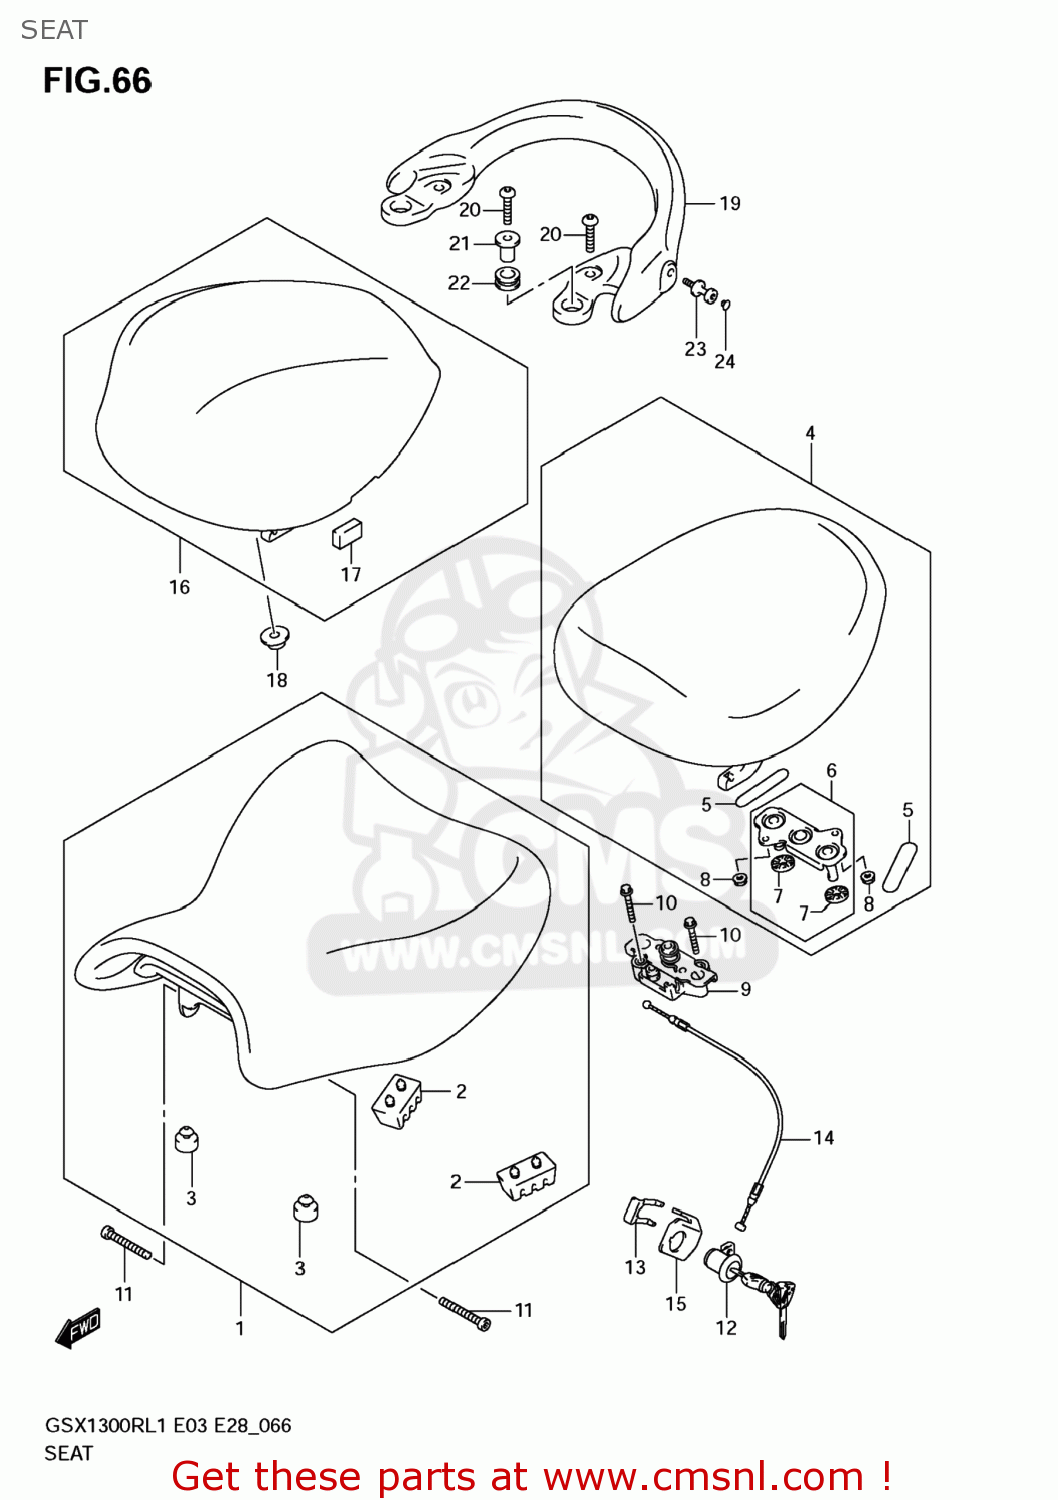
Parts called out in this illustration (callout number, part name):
1	SEAT ASSY
2	CUSHION,SUPPORT(50X25X32)
3	CUSHION
4	SEAT ASSY,PILL
5	CUSHION
6	STRIKER,SEAT LOCK
7	CUSHION
8	NUT
9	BRACKET,STRIKER SUPPORT
10	BOLT
11	BOLT,SEAT FR
12	LOCK SET,SEAT
13	PLATE,SEAT LOCK ASSY
14	CABLE,SEAT LOC
15	GUIDE,SEAT LOCK CABLE
16	BOX,SEAT TAIL(BLUE)
17	CUSHION
18	WASHER,FRAME COVER
19	HANDLE,PILLION RIDER
20	BOLT(8X33)
21	WASHER,PILLION
22	CUSHION,PILLION RIDER HANDLE
23	HOOK,PILLION RIDER HANDLE
24	CAP(OD:10)
